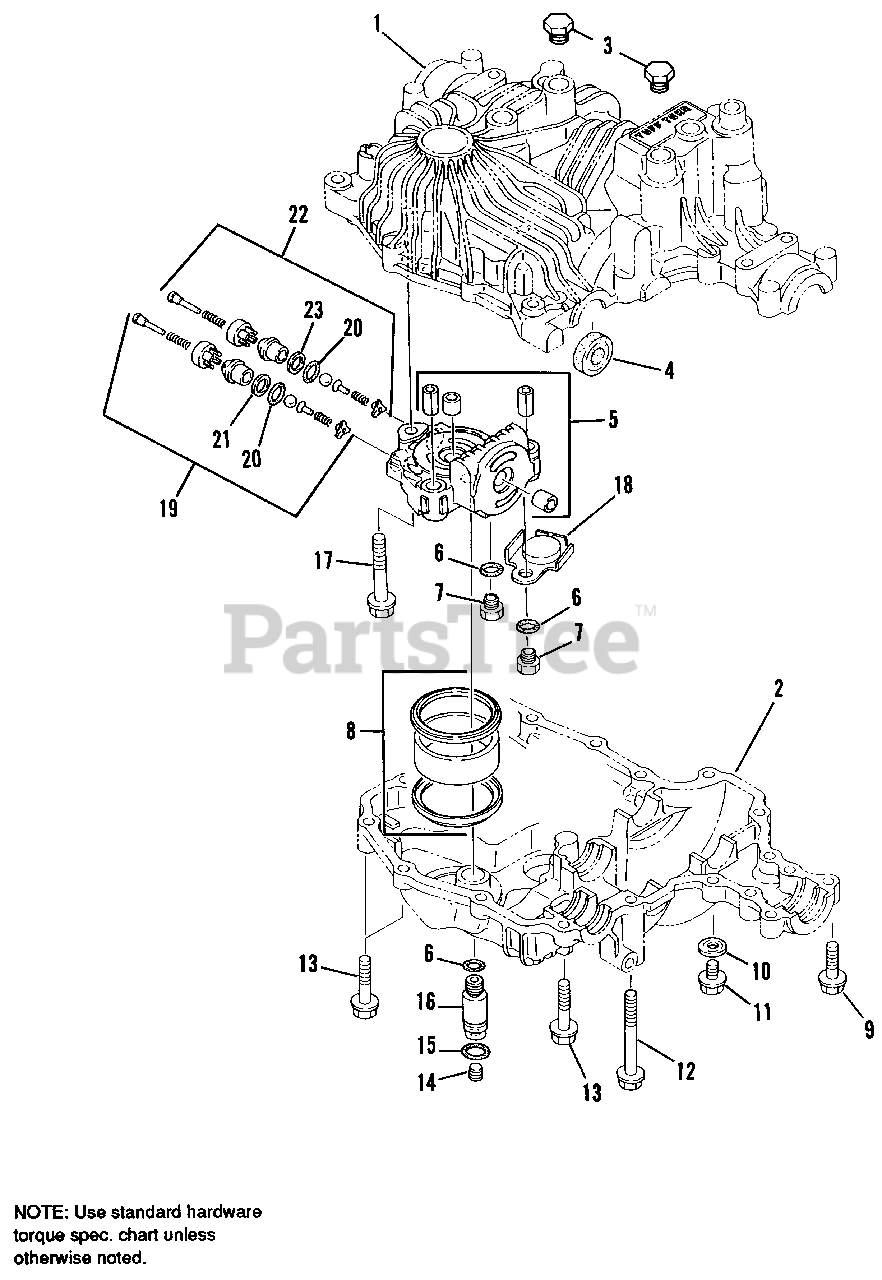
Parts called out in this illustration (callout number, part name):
1	COVER ASSY.
3	SEALING CAP
5	CENTER CASE ASSY.
9	SCREW, Self-Tapping
10	WASHER, Seal
13	SCREW, Self-Tapping
17	BOLT
19	VALVE (Incl. Ref. Nos. 20 & 21)
20	PACKING
21	RING, Back-up
22	VALVE (Incl. Ref. Nos. 23 & 24)
23	RING, Back-up
